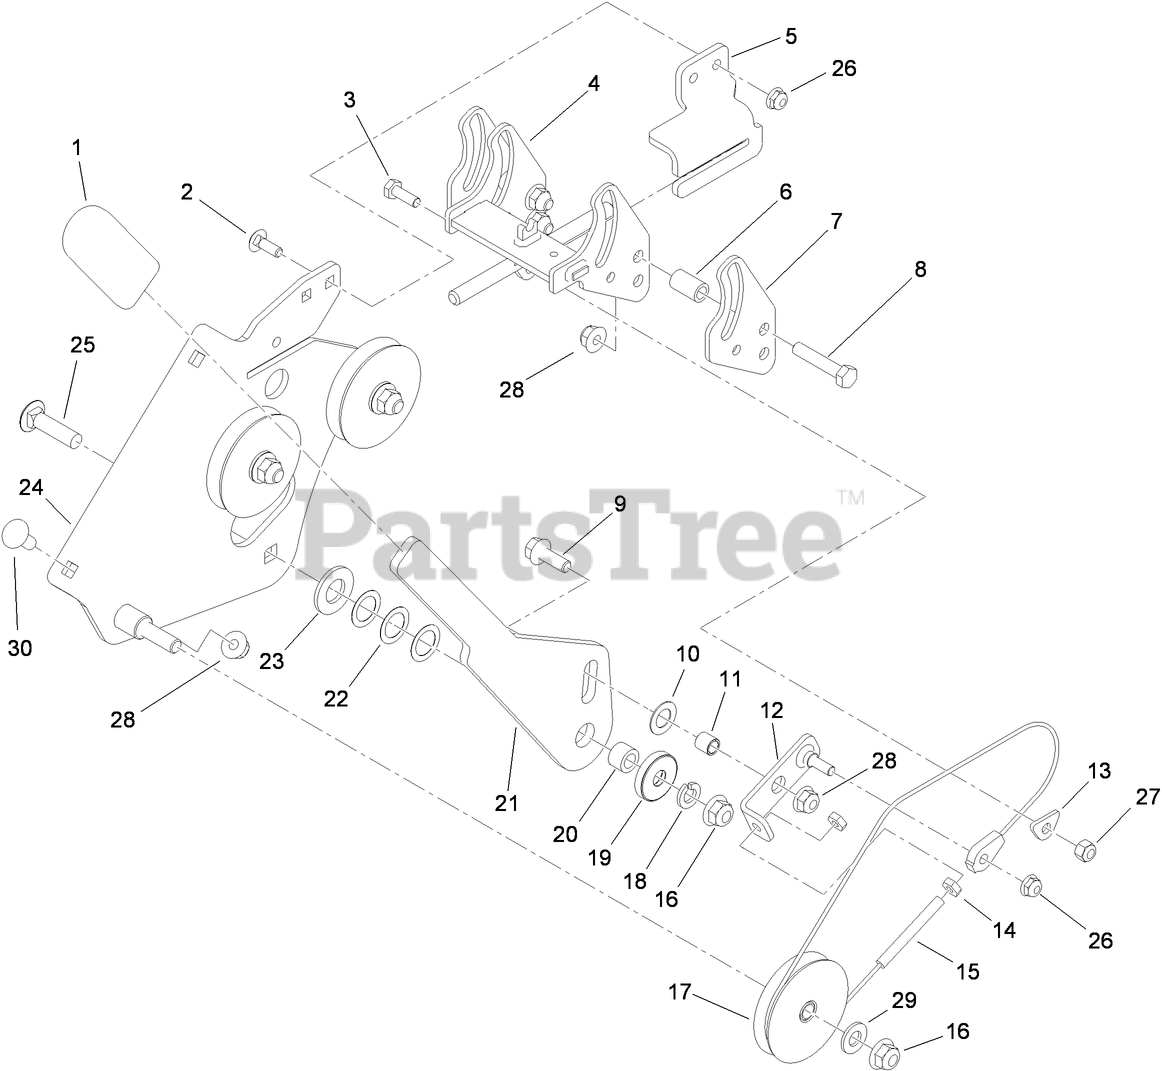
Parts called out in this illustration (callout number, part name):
2	BOLT-CARR
3	SCREW-HH
4	SLIDER ASM
5	BRACKET-SLIDER
6	SPACER-IDLER
7	PLATE-SLIDER
8	SCREW-HH
9	SCREW-HHF
10	WASHER-PLAIN
11	SPACER
12	LINK ASM
13	WASHER-CLAMP, CABLE
14	NUT-JAM
16	NUT-HF, NI
17	PULLEY ASM
18	WASHER-LOCK
19	RETAINER
20	SPACER
21	HANDLE-CONTROL, SPEED
22	WASHER-SPRING, CURVED
23	WASHER
24	SPEED CONTROL BASE ASM
25	SCREW-CARR
26	NUT-HF
27	NUT-LOCK, NI
28	NUT-HF, NI
29	WASHER-FLAT
30	BOLT-CARR
